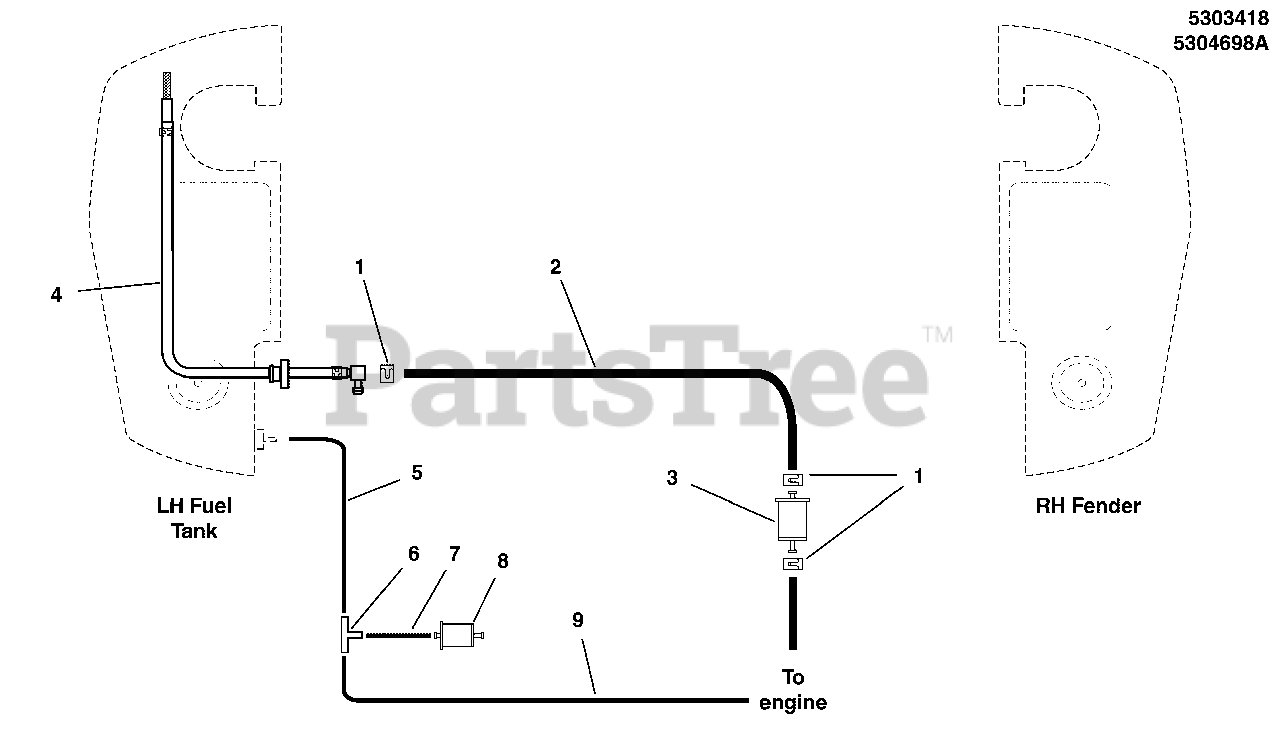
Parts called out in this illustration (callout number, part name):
1	CLAMP, HOSE, EXTERNAL, 1/2 - RED
2	HOSE, 1/4" FUEL, 23.00"
3	FUEL FILTER (SV)
4	ASSM, FUEL HOSE, 26
5	HOSE, VAPOR, 5MM ID, 34.00 LG
6	FITTING, 3/16" TEE, BARB TYPE, HDPE
7	HOSE, VAPOR, 5MM ID, 2.00 LG
8	FILTER, Fuel
9	HOSE, VAPOR, 5MM ID, 9.00 LG
